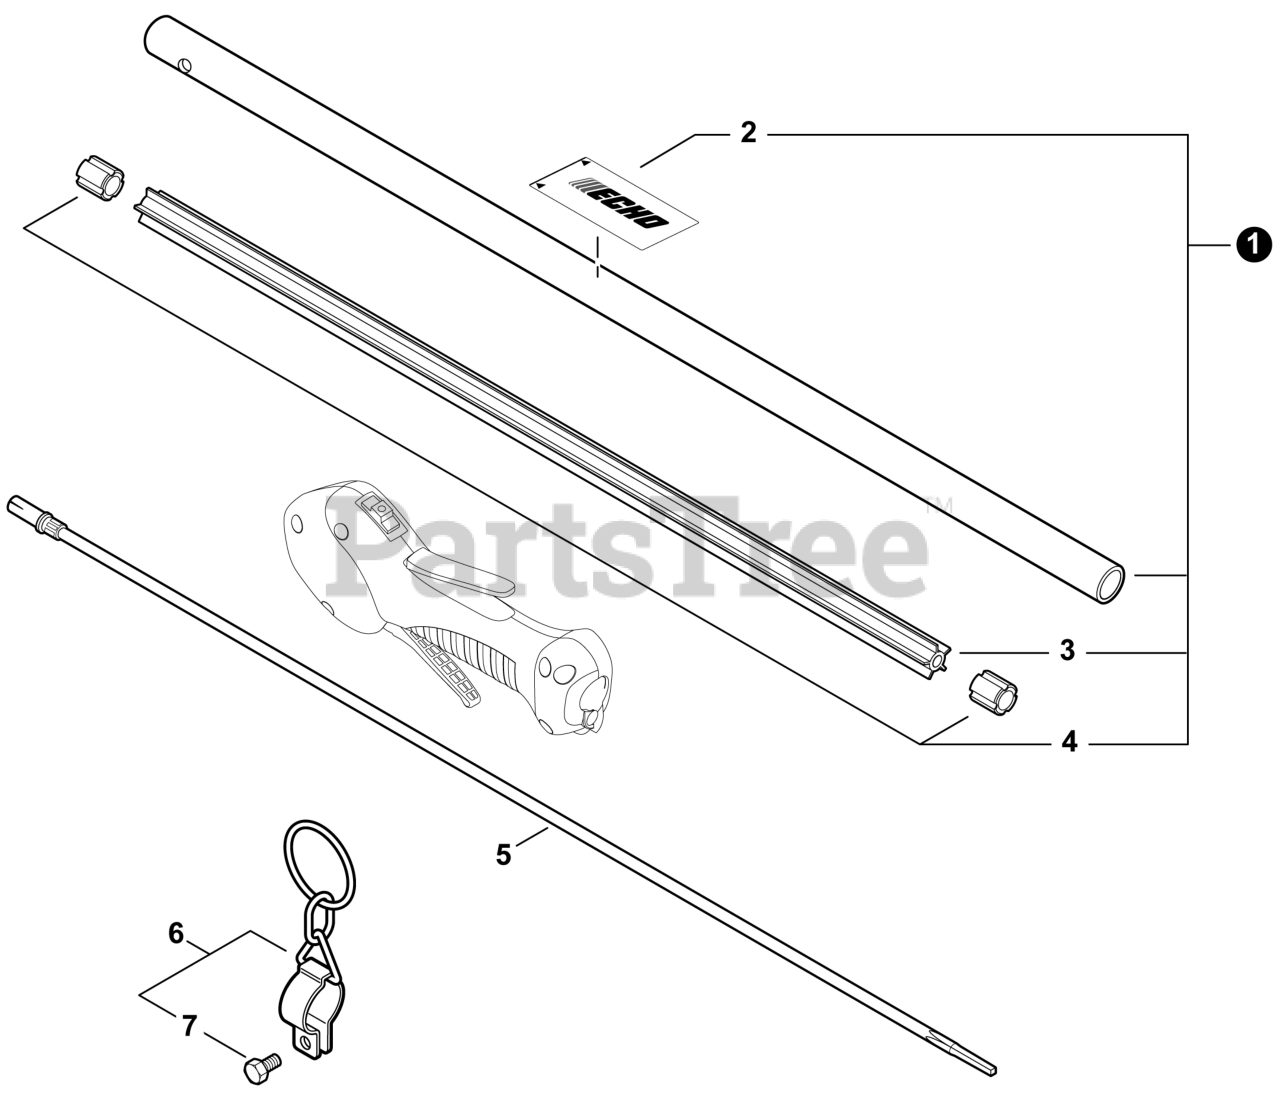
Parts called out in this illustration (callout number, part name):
1	MAIN PIPE ASSY
2	LABEL - HANDLE LOCATION
3	LINER - FLEXIBLE
4	STOPPER
5	DRIVESHAFT - FLEXIBLE
6	HANGER SET, HARNESS
7	BOLT, TORX 5x12
